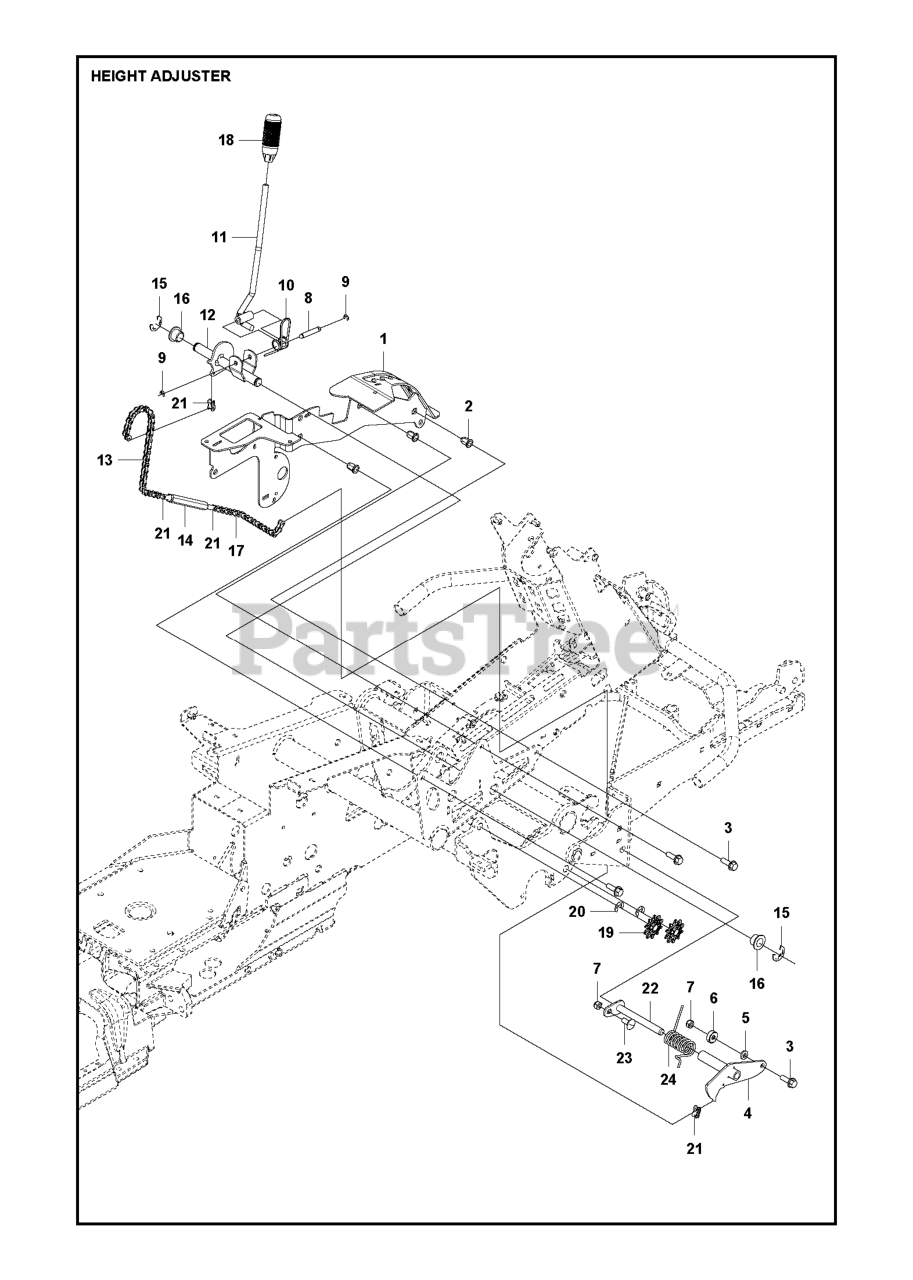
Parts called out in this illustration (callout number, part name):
3	BOLT
6	BALL BEARING
7	LOCKNUT M8
10	HAIR PIN SPRING
16	BEARING FLANGE
20	RETAINING RING
